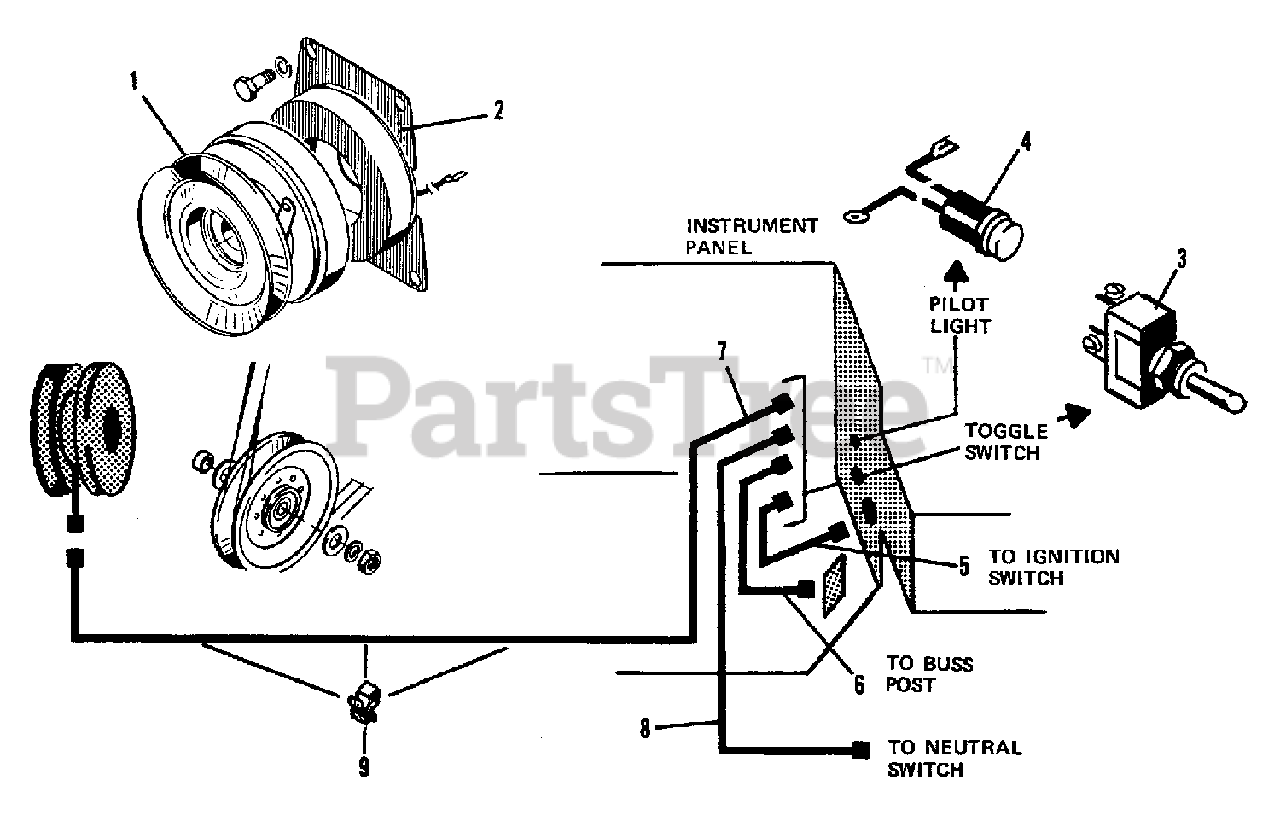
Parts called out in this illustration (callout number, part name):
1	HUB, Clutch
1	KEY, 1/4 x 1/4 x 5/8
2	COIL, Clutch
2	CAPSCREW, 7/16NC x 3/4
2	LOCKWASHER, 7/16
3	SWITCH, Toggle (Screw Type Terminals)
3	SWITCH, Toggle (Slide Type Terminals)
4	LIGHT, Pilot (Used With Screw Type Terminals)
4	LIGHT, Pilot (Used With Slide Type Terminals)
5	*LEAD, Ignition Switch To PTO Switch (Used With Screw Type Terminals On Breakerless Ignition System Only)
5	*LEAD, Ignition Switch To PTO Switch (Used With Screw Type Terminals With Breaker Point Ignition)
5	**LEAD, Ignition Switch to PTO Switch (Used With Slide Type Terminals Only)
6	*LEAD, Buss Post to Switch (Used With Screw Type Terminals)
6	**LEAD, Buss Post To Switch (Used With Slide Type Terminals)
7	*LEAD, Clutch To Switch (Used With Screw Type Terminals)
7	**LEAD, Clutch To Switch (Used With Slide Type Terminals)
8	*LEAD, To Transmission Switch (Used With Screw Type Terminals)
8	**LEAD, To Transmission Switch (Used With Slide Type Terminals)
9	CLIP, #3 Closed
